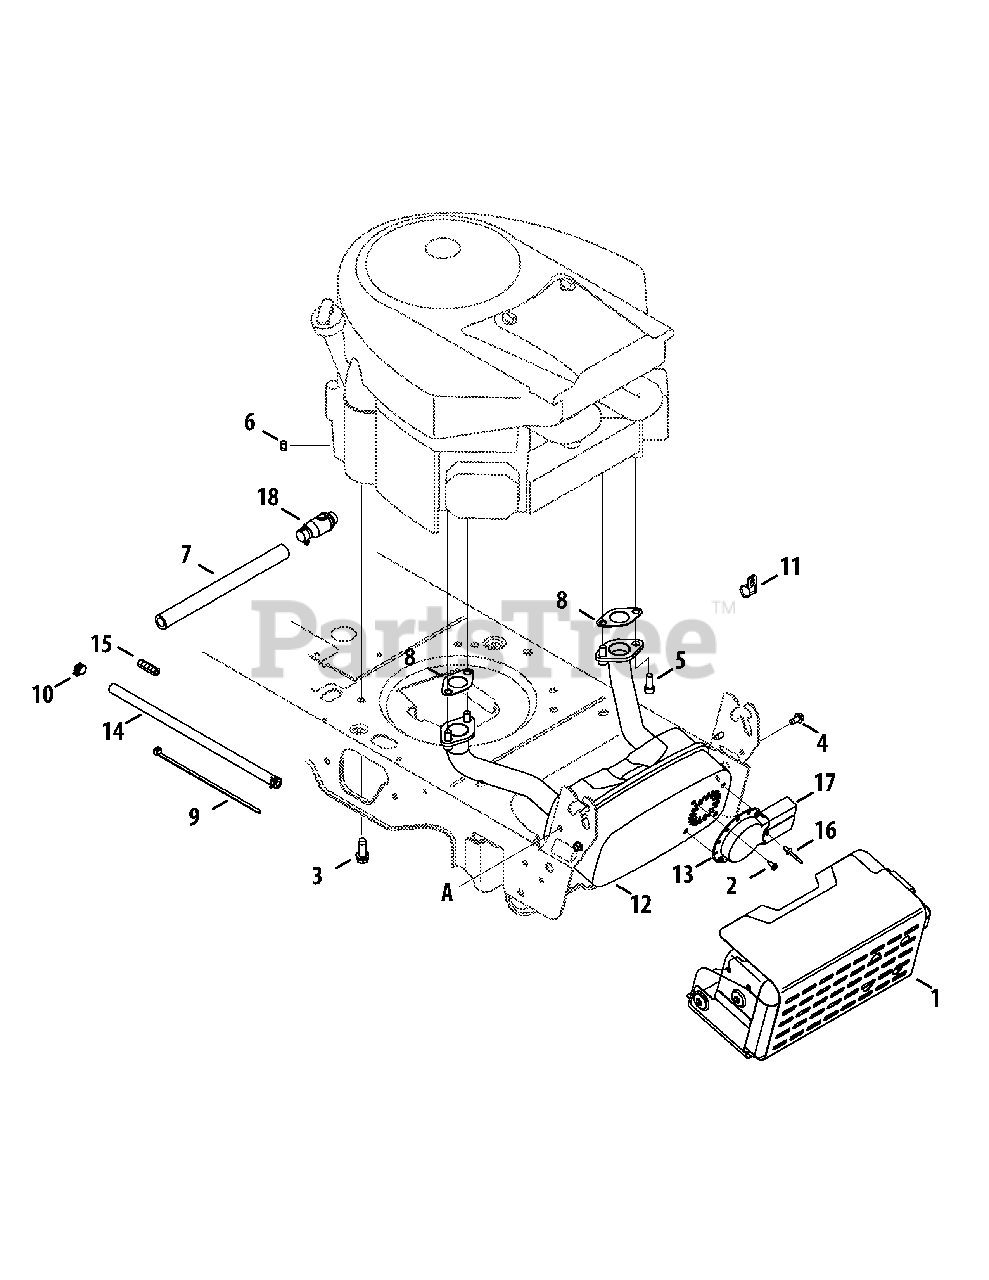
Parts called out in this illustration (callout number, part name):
1	Shield Ass’y, Muffler
2	Screw, Ab, #8-18, 0.500,
3	Screw, Self-tapping, 3/8-16, 1.000,
4	Screw, Self-tapping, 1/4-20, 0.500,
5	Screw, Socket Head, 5/16-18, .750
6	Nut, Sems, 1/4-20
7	Hose, Extension, Oil Drain
8	Gasket, Exhaust, Kawasaki
9	Cable, Tie, 3/16 x .05 x 7.4
10	Clamp, Hose, .490 Dia.
11	Clamp, 9/16 Dia.
12	Muffler, Kawasaki Twin
13	Deflector, Muffler
14	Hose, Fuel, Low Permeation, 1/4
16	Rivet, Pop, .188 Dia x .300
17	Deflector, Muffler, Long
18	Drain, Oil
